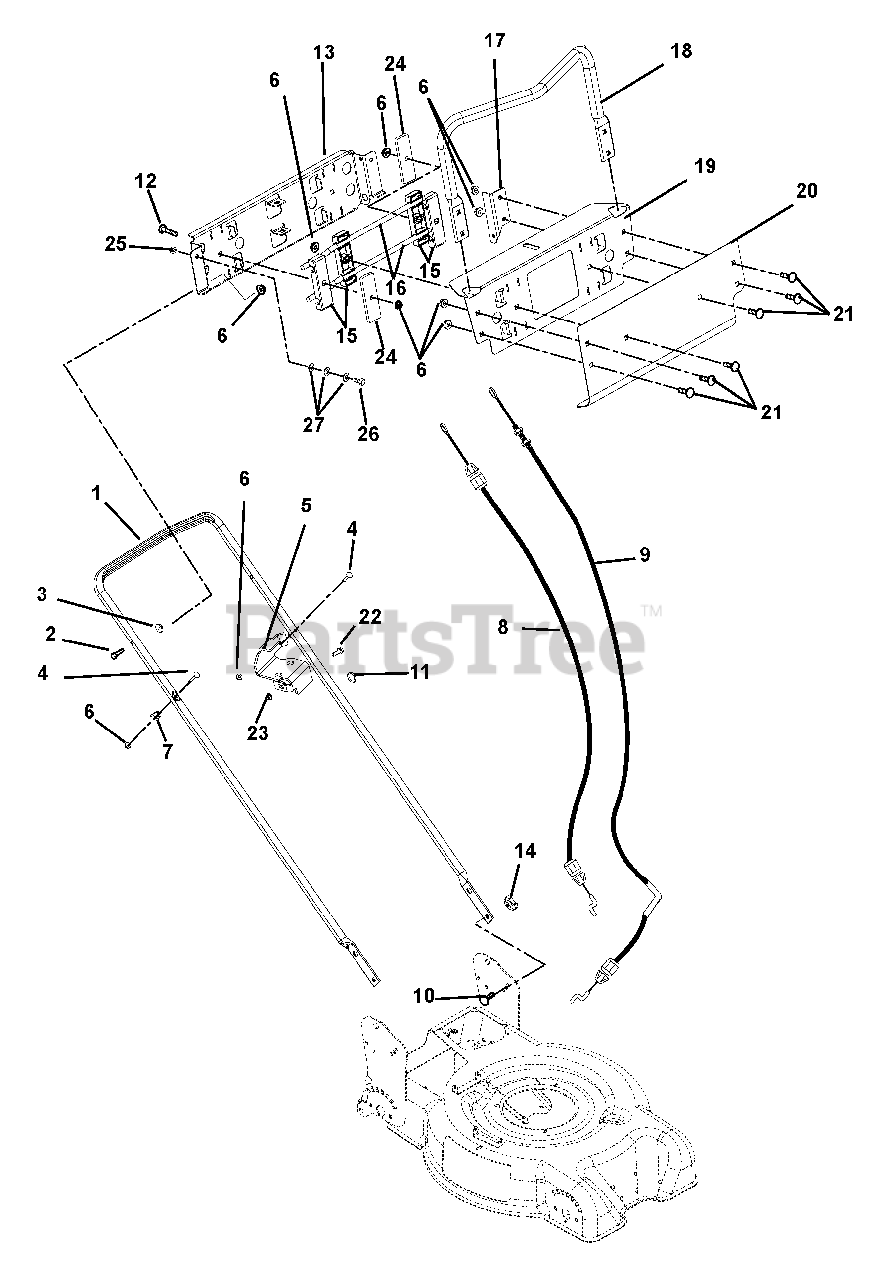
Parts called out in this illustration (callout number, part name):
1	HANDLEBAR, WBLM
2	@BLT-HEX .25-20X1.75 GR5 YWZC
3	BSHG-FLG .265X.437X.250X.750
4	BLT-RDHDXLSQNK.25-20X1.25 G5ZC
5	ANCHOR, CABLE - THUMB ADJUST
6	@NUT-LK-TOP-FLG .25-20 YWZC
7	GUIDE - PULLCORD
8	CABLE, OPERATOR PRESENCE (DLX)
9	CABLE, TRACTION - THUMB-ADJUST
10	@BLT-RHDSSQNK .31-18X.75 G5YZ
11	CONDUIT CLIP
12	@BLT-RDHDSQNK .25-20X1.00 G5YZ
13	PLATE,HINGE
14	KNOB-CLAMPING, .312-18 NYLOC
15	CLAMP,4-BAR
16	ROD,4-BAR
17	BKT,CABLE ANCHOR
18	BAIL .750 TUBE
19	COVER,OP CONTROL
20	BRKT, HOOD LH
21	@BLT-RDHDSQNK .25-20X1.00 G5YZ
22	@BLT-HEX .25-20X1.25 GR5 YWZC
23	@NUT-LK-TOP-FLG .25-20 YWZC
24	PLATE, STIFFENING
25	@NUT-LK-NYL .250-20 YWZC
26	@BLT-HEX .25-20X.50 GR5 YWZC
27	@WSHR-FL-STL.250X.56X.049 YWZC
